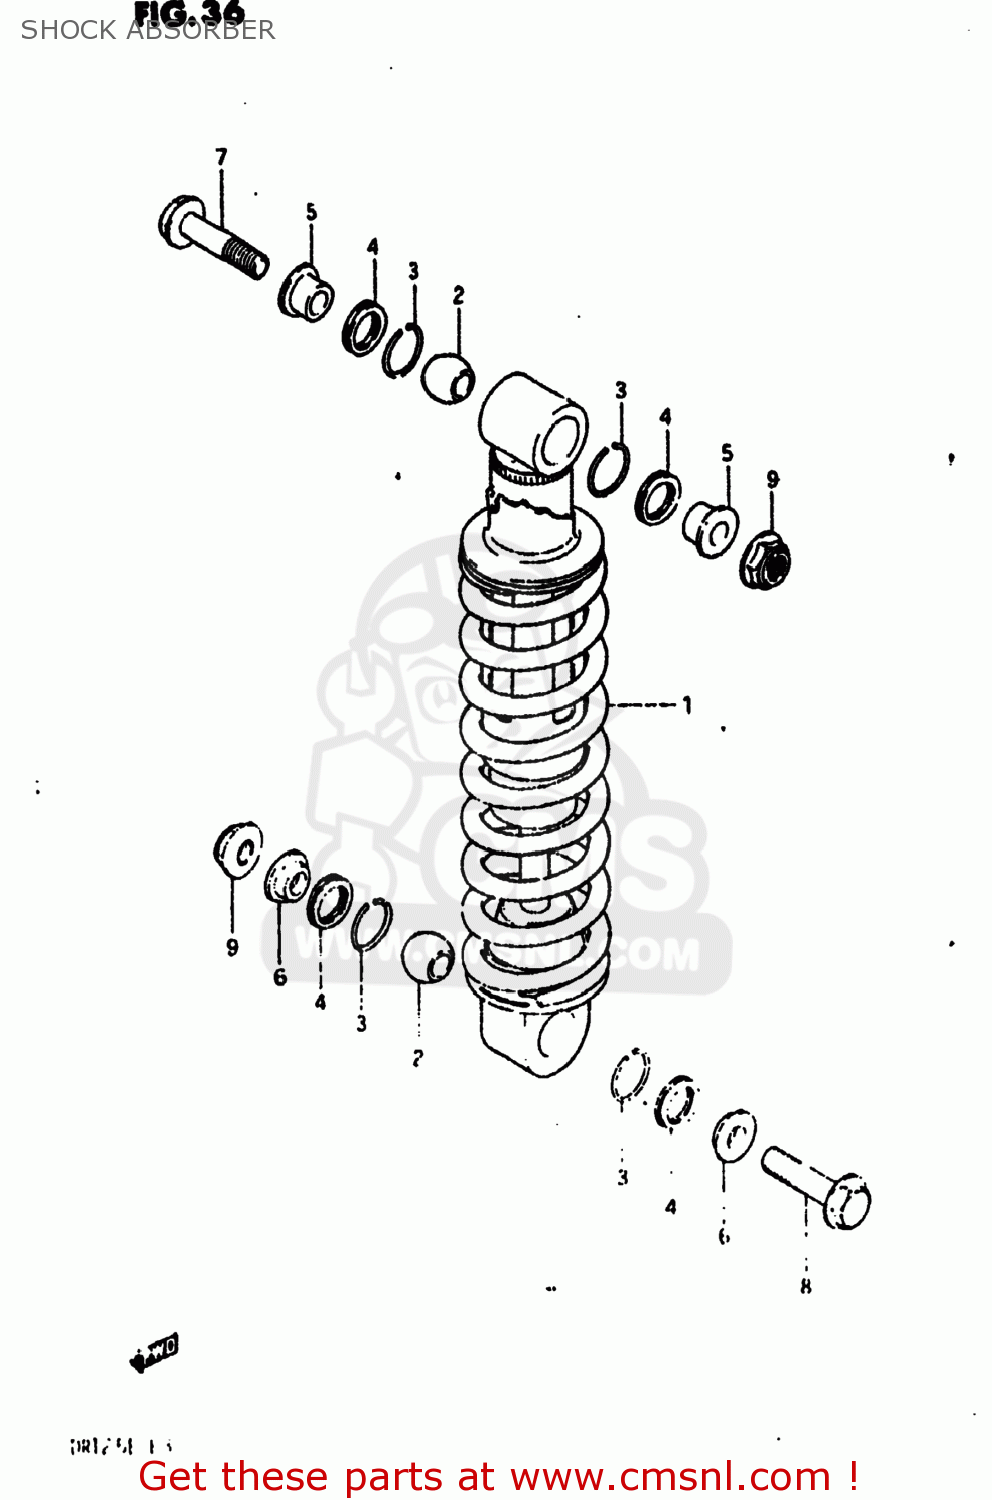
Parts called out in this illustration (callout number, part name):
1	ABSORBER ASSEMBLY,REAR SHOCK
2	BEARING,REAR SHOCK ABSORBER
3	RING
4	DUST SEAL
5	COLLAR,UPR
6	COLLAR,LWR
7	BOLT
8	BOLT(10X50)
9	NUT
